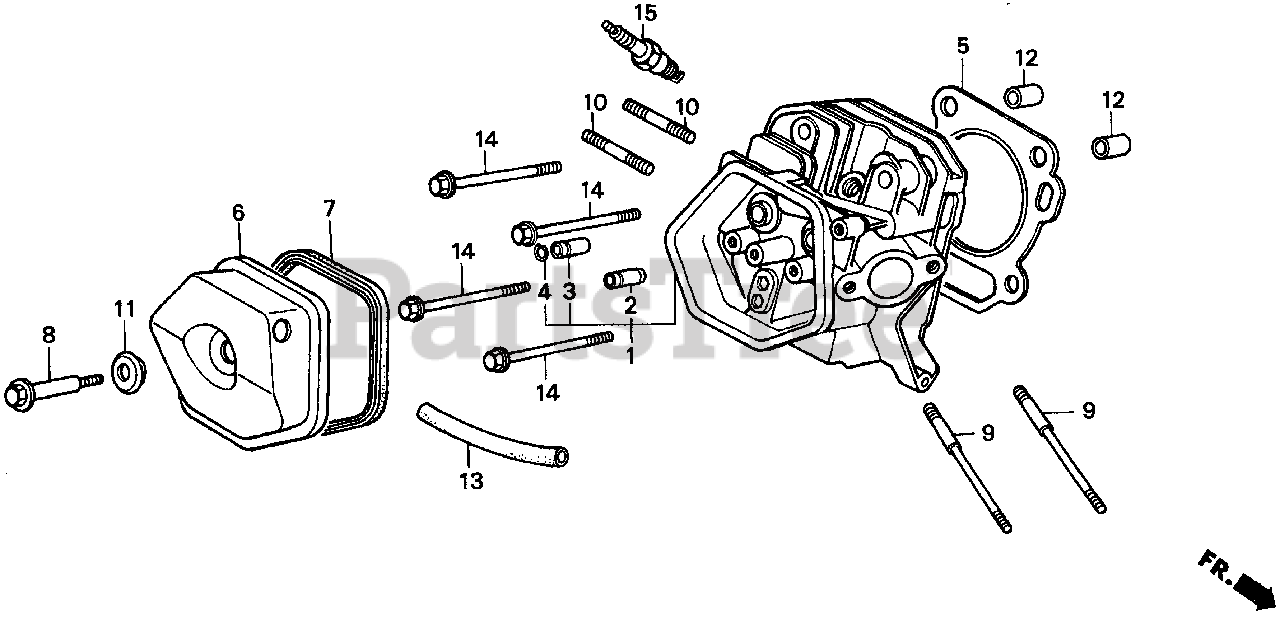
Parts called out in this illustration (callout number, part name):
1	CYLINDER HEAD
2	GUIDE, VALVE (OS)
3	GUIDE, EX. VALVE (OS)
4	CLIP, VALVE GUIDE
5	GASKET, CYLINDER HEAD
6	COVER, HEAD
7	GASKET, CYLINDER HEAD COVER
8	BOLT, HEAD COVER
9	BOLT, STUD (8X131.5)
10	BOLT, STUD (8X47)
10	BOLT 2, STUD (8X32)
11	WASHER, HEAD COVER
12	PIN A, DOWEL (12X20)
13	BULK HOSE, VACUUM (11X1000) (11X105)
14	BOLT, FLANGE (10X80)
15	SPARK PLUG (BPR5ES) (NGK)
15	SPARK PLUG (W16EPR-U) (DENSO)
15	SPARK PLUG (BPR6ES) (NGK)
15	SPARK PLUG (W20EPR-U) (DENSO)
